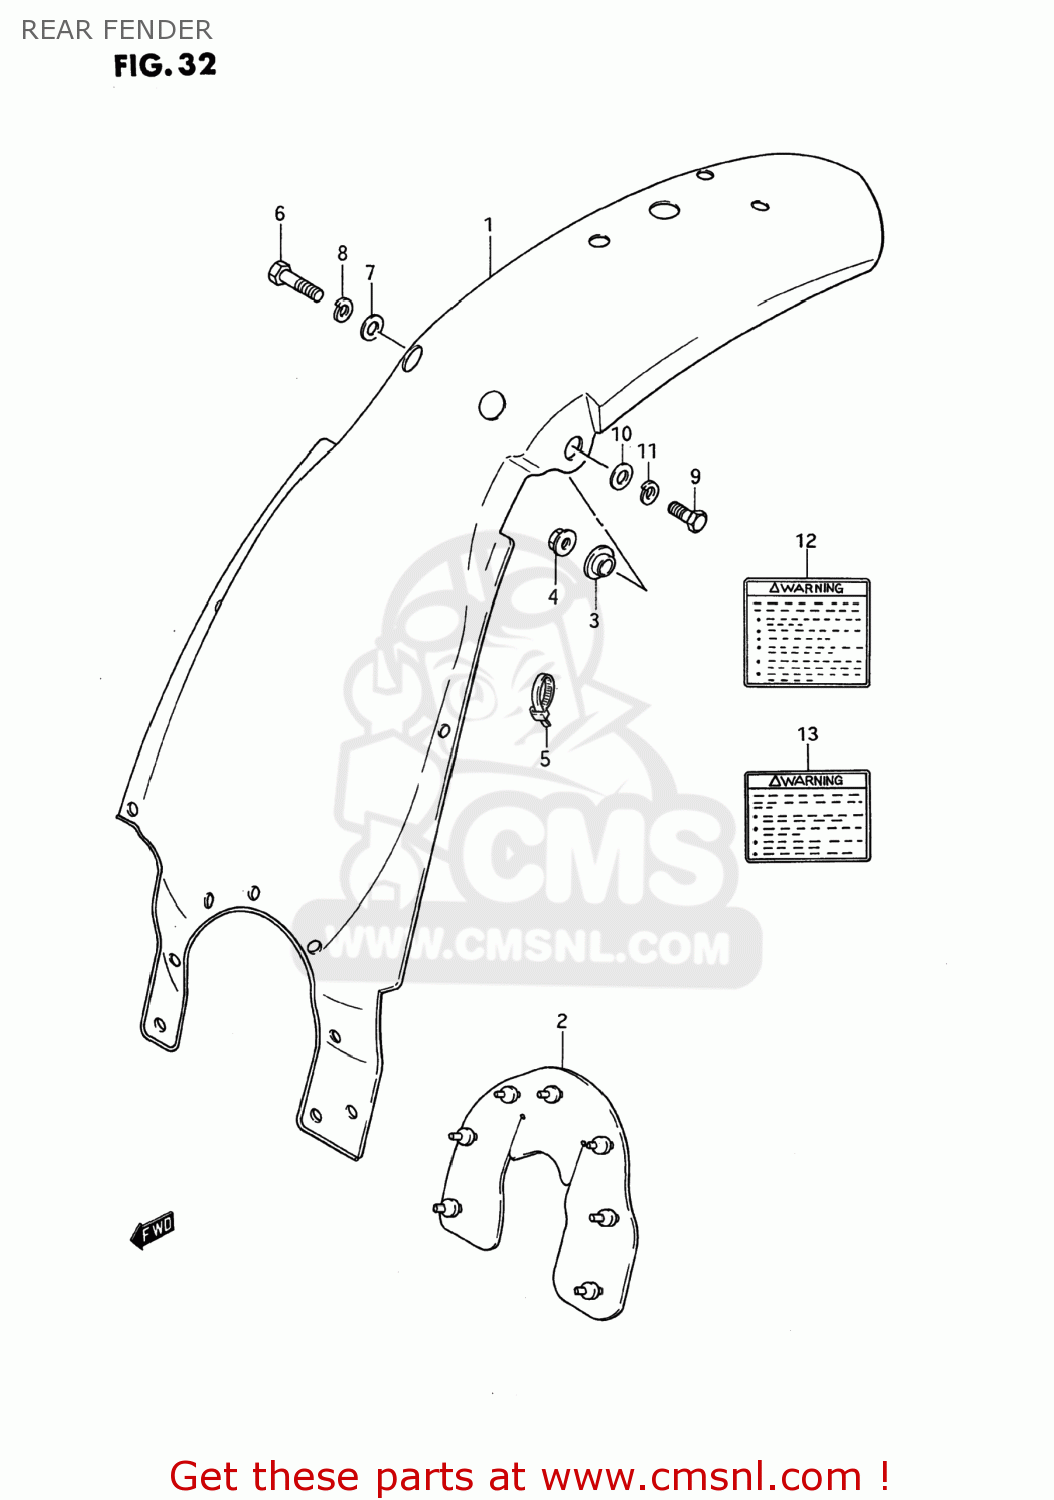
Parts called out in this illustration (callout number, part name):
1	FENDER,RR
2	MUDGUARD,RR FENDER
3	WASHER
4	NUT
5	CLAMP
6	BOLT
7	WASHER (8.5X29X1.6)
8	LOCK WASHER
9	BOLT
10	WASHER
11	WASHER,LOCK,8.
12	LABEL (WARNING)
13	LABEL
14	MANUAL,OWNER'S
